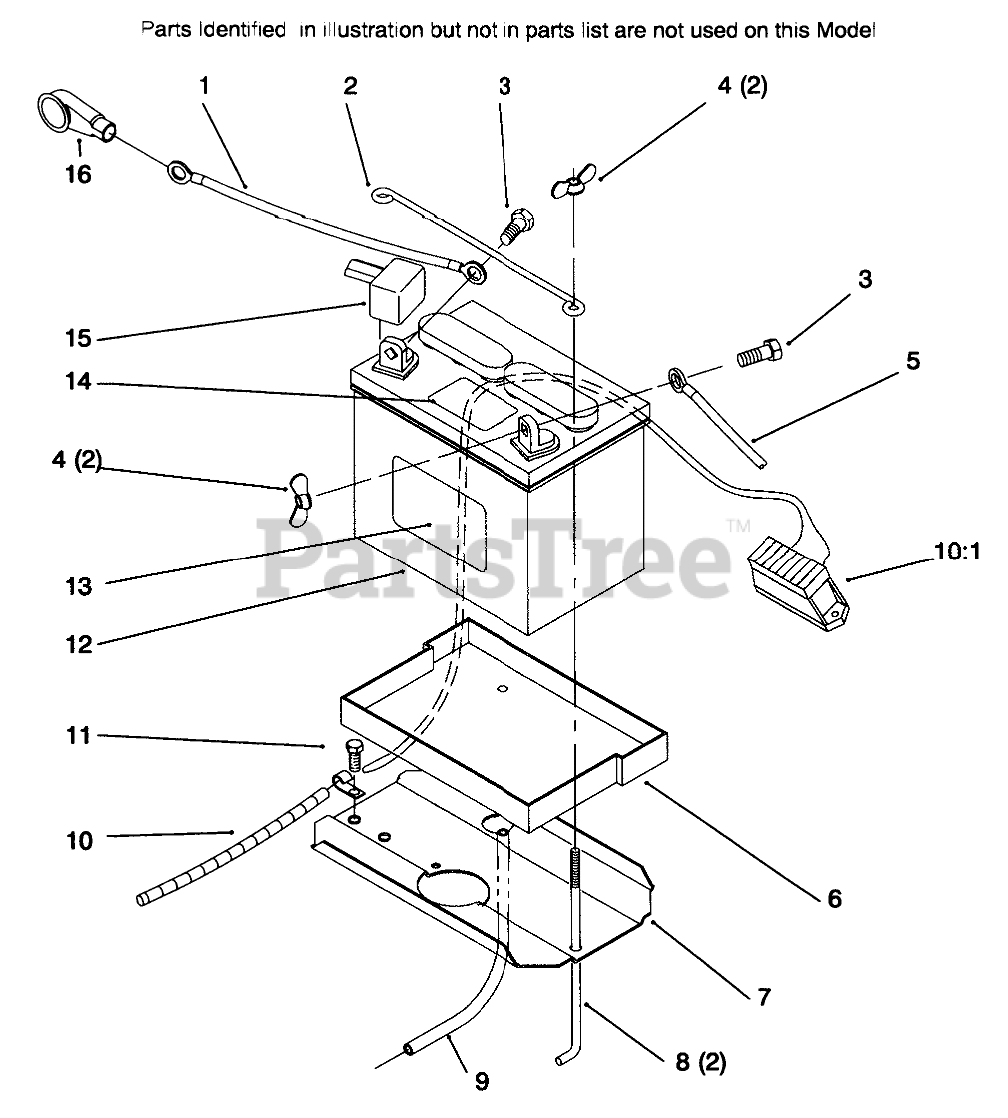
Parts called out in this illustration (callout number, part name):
1	WIRE-21 INCH
2	ROD-BATTERY HOLD DWN
3	SCREW-HH
4	NUT-WING
5	CABLE
6	TRAY-BATTERY
7	Plate-Battery
9	TUBE-21" BATTERY DRAIN
10	HARNESS - WIRE 17H
10:1	FUSE-HOLDER 4 WAY
11	Screw-HH
12	Battery
13	Decal-Battery Charge Ins (Only On: 72104)
14	Decal-Danger (Only On: 72104)
15	Boot
16	BOOT-INSULATOR, TERMINAL
